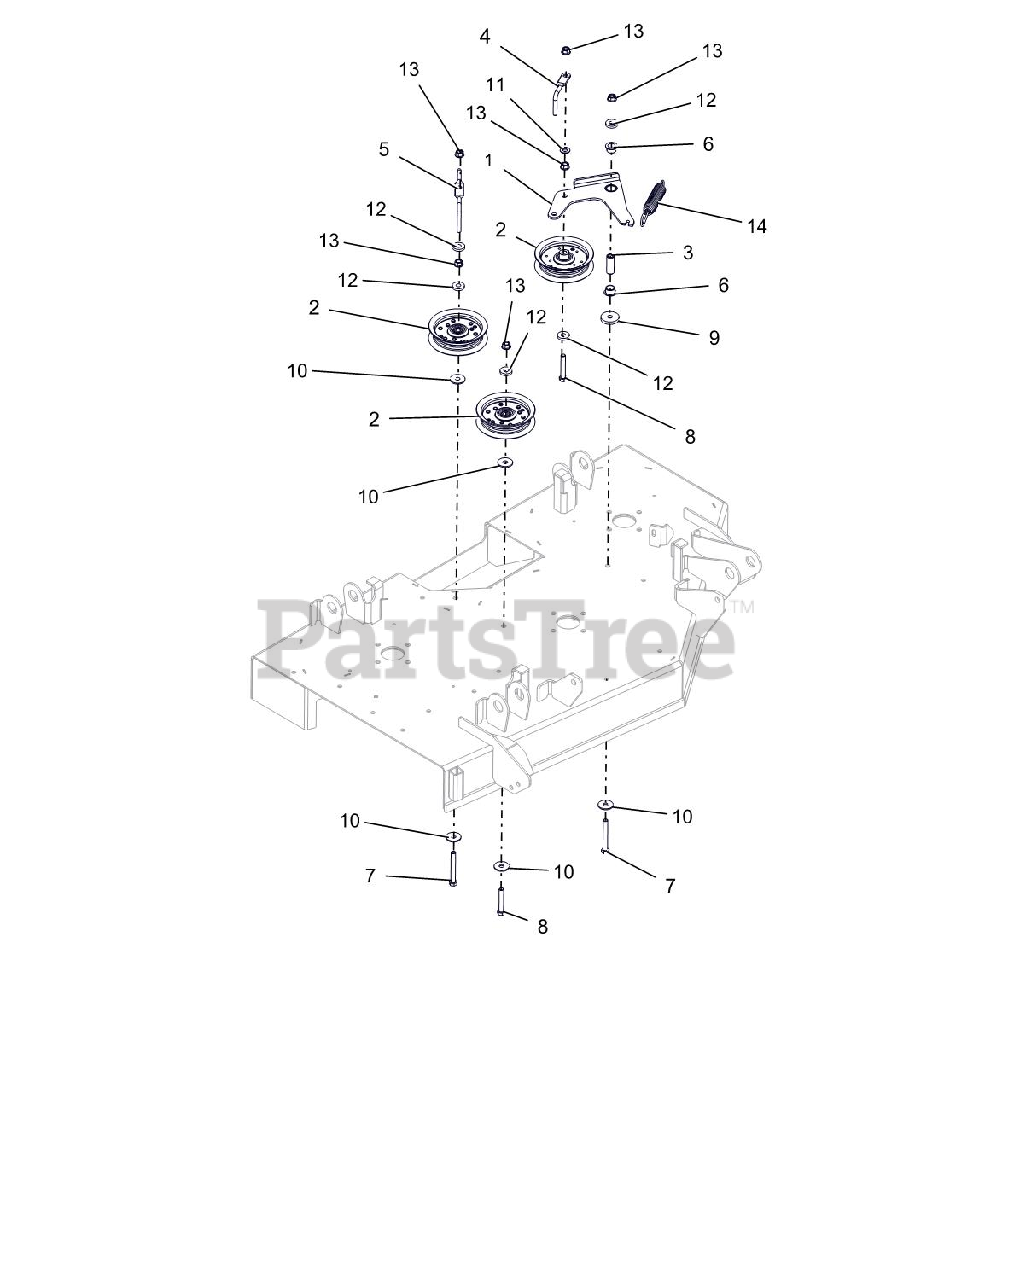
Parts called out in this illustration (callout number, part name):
1	WLDMT, IDLER ARM-42"
2	ASM, IDLER 4"
3	SPACER, .375IDX.625ODX1.66 PM
4	WIREFORM, BELT FINGER
5	BELT FINGER
6	BSHG-FLG, .625X.750X.500X1.00
7	BLT-HEX .38-16X3.00 GR5 FTH YZ
8	BLT-HEX .38-16X2.25 GR5 YWZC
9	WSHR,FLT STL.406X1.50X.245YWZC
10	WSHR-FL-STL .406X1.25X.10 ZC
11	WSHR-FL-STL.406X.812X.065 YWZ
12	WSHR-FL-STL .406X1.00X.188 YWZ
13	NUT-LK-TOP-FLG .38-16 YWZC
14	SG-TENS .135X.98X6.0 WLD 62
